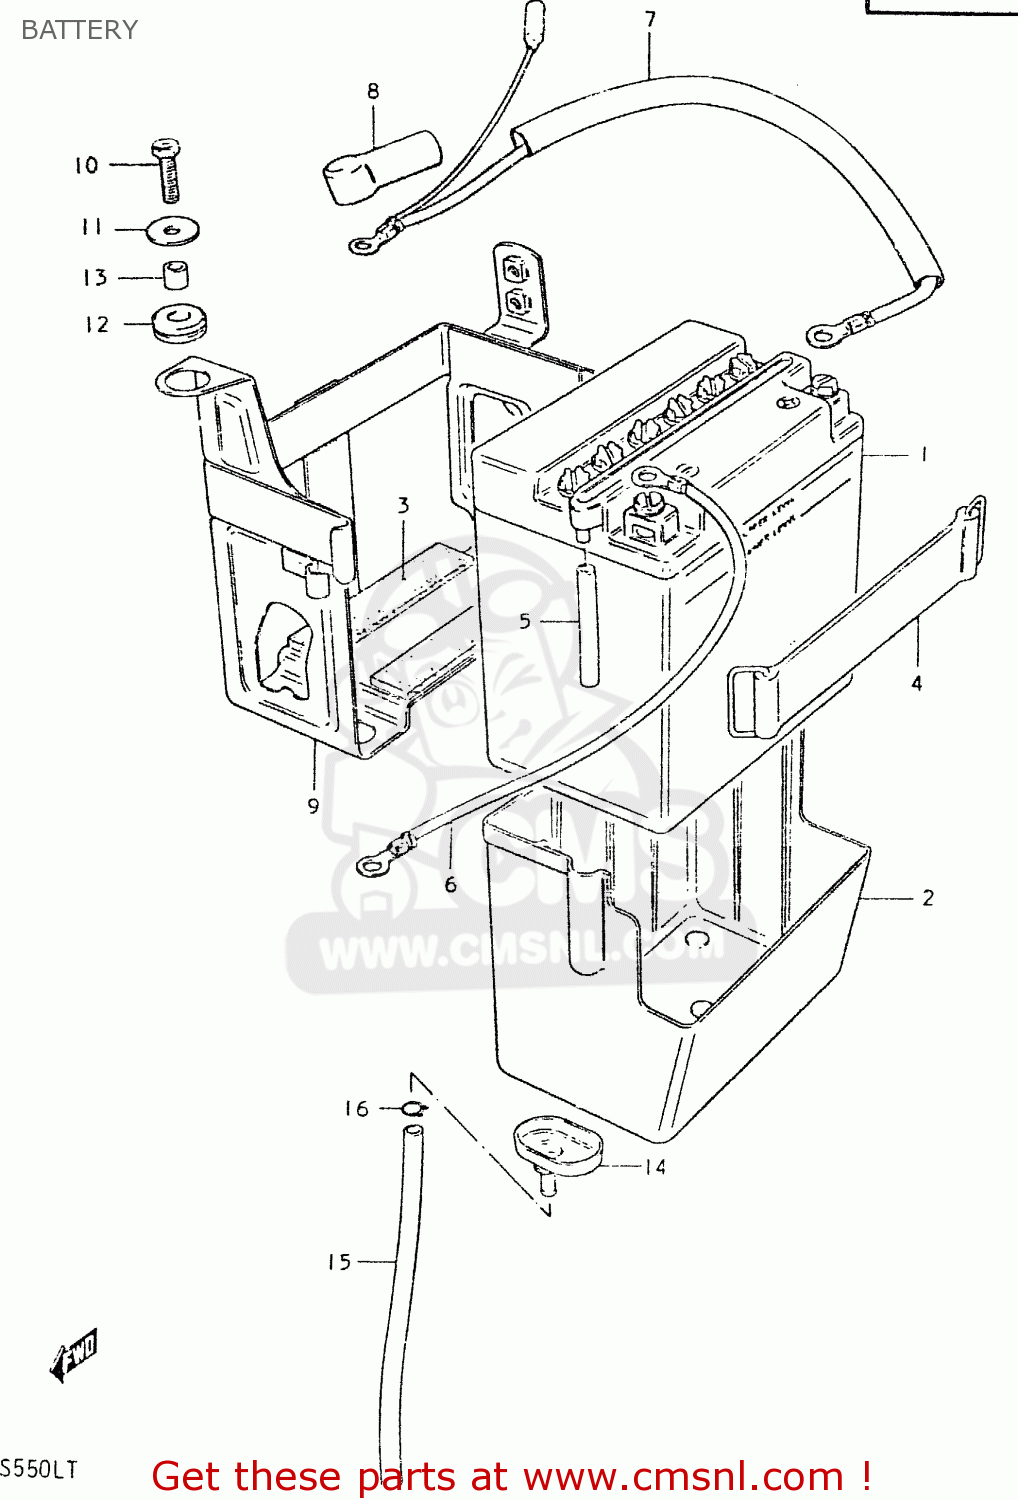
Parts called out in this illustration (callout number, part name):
1	BATTERY ASSY (12V)
2	CASE,BATTERY
3	PROTECTOR,20X9
4	BAND
5	HOSE, EXHAUST (L:45)
6	WIRE,STARTER MOTOR LEAD
7	WIRE,BATTERY PLUS
8	CAP,TERMINAL
9	HOLDER,BATTERY
10	BOLT(6X20)
11	WASHER
12	CUSHION
13	SPACER(6.1X9X7.5)
14	FUNNEL,BATTERY EXHAUST
15	HOSE,BATTERY EXHAUST
16	CLIP
